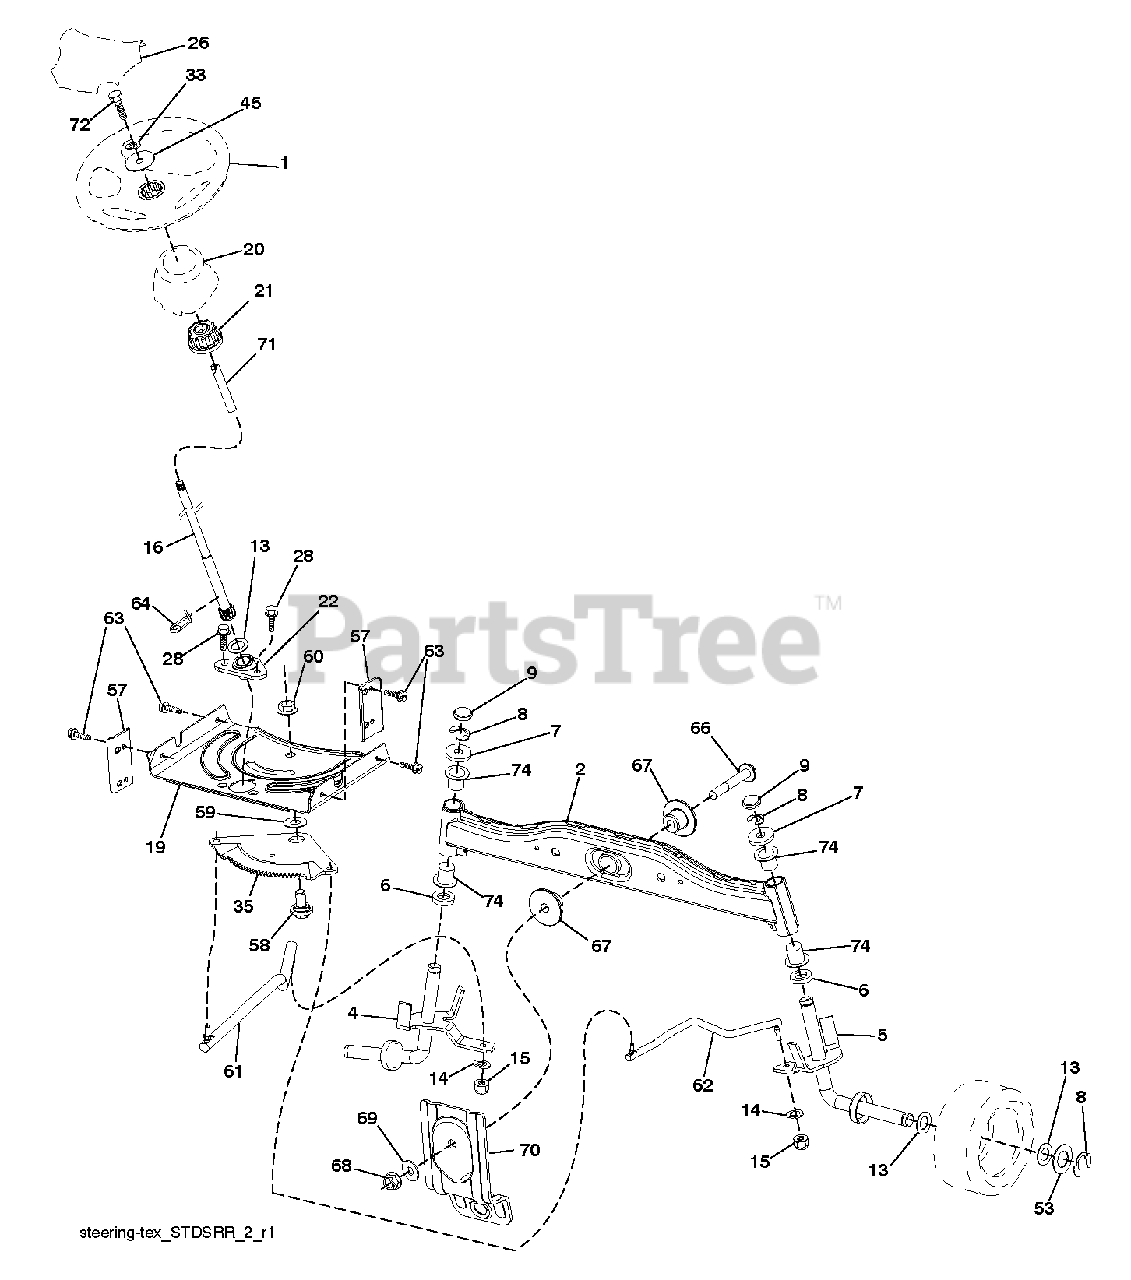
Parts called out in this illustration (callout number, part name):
1	WHEEL.STEERING.STDSRR.BLK/OV
2	AXLE HALF ASM-WELDED
4	SPINDLE.WELDED.LH.15"TEX
5	SPINDLE.WELDED.RH.15"T
8	RING CLIP
9	CAP.SPINDLE
14	WASHER, LOCK 3/8
15	NUT CROWNLOCK 3/8-24
16	SHAFT.STEER.3/4.PLATED.TEX
19	PLATE.STEER.DDL.NLT/NG
20	BOOT.STEERING.PREDATOR.LT.BLAC
21	ADAPTER, WHEEL STNG..
22	STEERING.SUPT.LOWER.
26	CAP.WHL.STRNG.STDSRRD.SRS.BLK
28	SCREW, 3/8-16X3/4
33	LOCKWASHER
35	GEAR.SECTOR.PLATE.DDL.
45	WASHER.11/32
53	WASHER.HARDENED
57	BRACKET.UPSTOP.TEX
58	BOLT.SHOULDER.SECTOR.P
59	WASHER.THURST.SECTOR.S
60	NUT FLANGE LOCK 5/8-11
61	DRAGLINK.LH.BALLSTUD.D
62	DRAGLINK.RH.BALLSTUD.D
63	SCREW
64	RETAINER.CLIP.SPRING.S
66	BOLT HEX FGHD 7/16-14 X 3 SERR
67	BUSHING.PM.FRONT AXLE
68	NUT.LOCK.FLANGE.7/16
69	WASHER.1.5X.505X.118
70	BRKT.DECK.SUSPENSION.F
71	SHAFT.EXTEN.STRG.SPLINE
72	BOLT 5/16-18 X 4 W/PATCH
74	BRNG T
